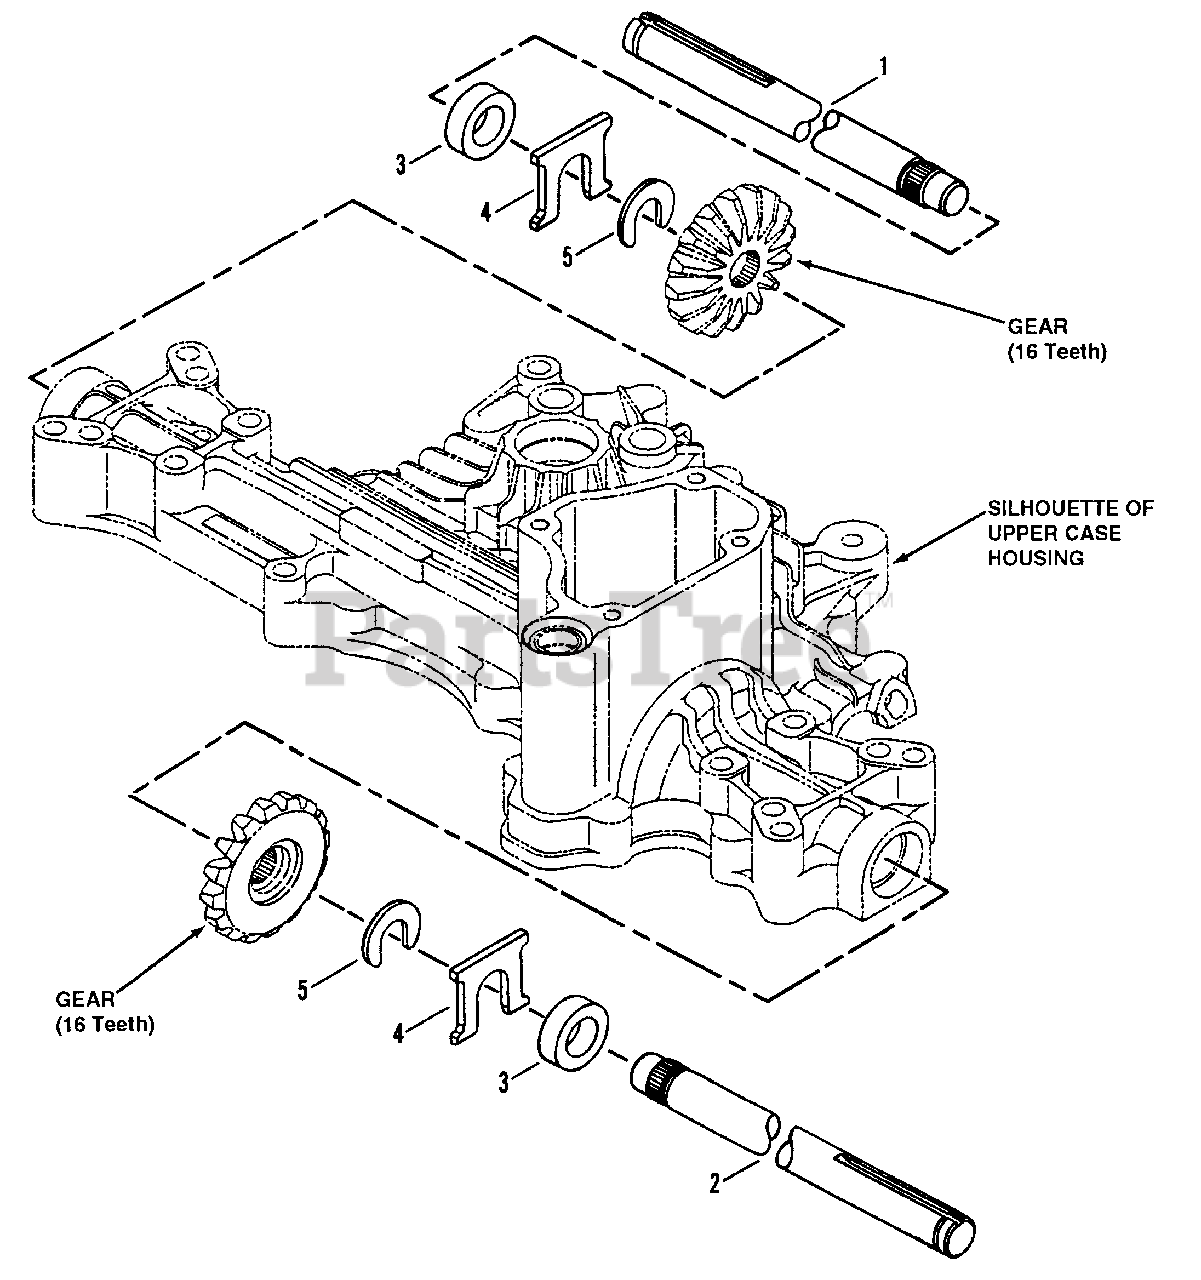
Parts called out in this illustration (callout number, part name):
1	SHAFT, Axle (Left Side)
2	SHAFT, Axle (Right Side)
3	SEAL, Axle Shaft
4	WASHER, Thrust
5	RETAINER, C-Ring
